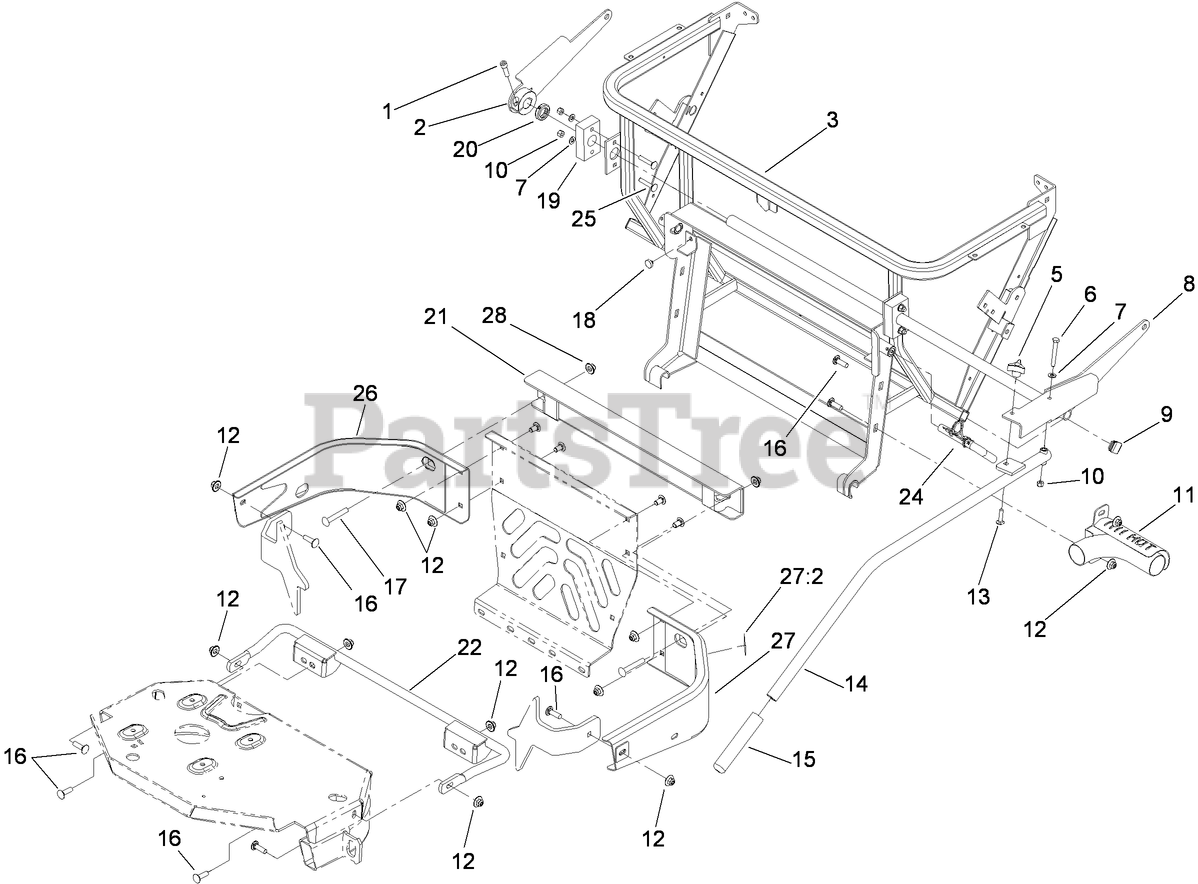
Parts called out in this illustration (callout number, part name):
1	SCREW-HSH
2	LINK
3	FRAME ASM
5	KNOB-3 PRONG
6	SCREW-HH
7	WASHER-PLAIN
8	BELLCRANK
10	NUT-LOCK, NI
11	DIVERTER-EXHAUST
12	NUT-FLANGE, NI
13	SCREW-CARR
14	HANDLE ASM
15	HANDLE-GRIP
16	SCREW-CARR
17	SCREW-CARR
18	BUMPER
19	BEARING
20	SHAFT-COLLAR
21	MOUNT-BAGGER, UPPER
22	MOUNT-BAGGER, LOWER
24	PIN-MOUNT, BAGGER
25	SCREW-CARR
26	BUMPER-RH
27	LH BUMPER ASM
27:2	DECAL-CAUTION
28	NUT-LOCK
